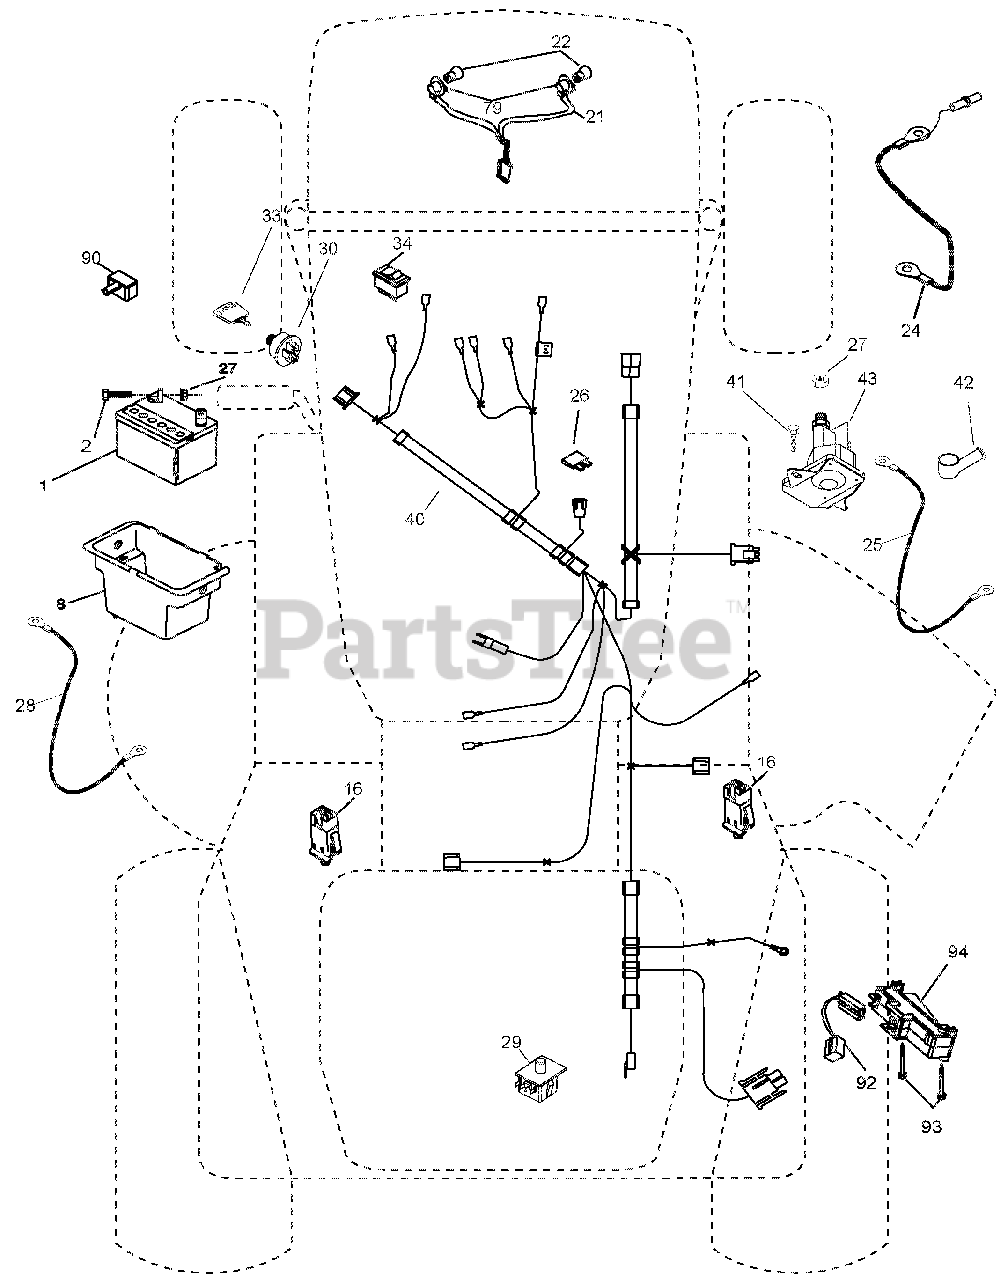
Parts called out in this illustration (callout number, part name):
1	BATTERY.12.VOLT.28.AMP.WET
2	BOLT.HEX.HD.1/4-20UNC X 3/4
8	Box Battery
16	SWITCH.INTERLOCK.NONO.GRAY
21	HARNESS ASM.LIGHT.22"(4152J)
22	BULB.LIGHT.#1156
24	Cable Battery 6 Ga. 11" Red
25	Cable Battery
26	FUSE.20 AMP.
27	Nut, Keps Hex 1/4-20 unc
28	Cable Ground 6 Ga. 12" Black
29	SWITCH.SEAT.DP.W/ROS
30	SWITCH.IGN.DLTA.P-IN.ROS
33	KEY/CHAIN.BLISTER PACK.GEN.USA
34	SWITCH.LIGHT/RESET.B/B/RED.
40	Harness Ign
41	Bolt Blk Fin Hex 1/4-20
42	COVER.TERMINAL.RED
43	SOLENOID.W/BRASS PLUNGER.2005
79	SOCKET ASM.BULB.TWISTLOCK
90	COVER TERMINAL BATTERY FR. TEX
92	HARNESS.PIGTAIL.CONSLE.ROS.MLK
93	SCREW.PLASTITE.10-14 X 2.0
94	MODUAL REVERSE ROS
